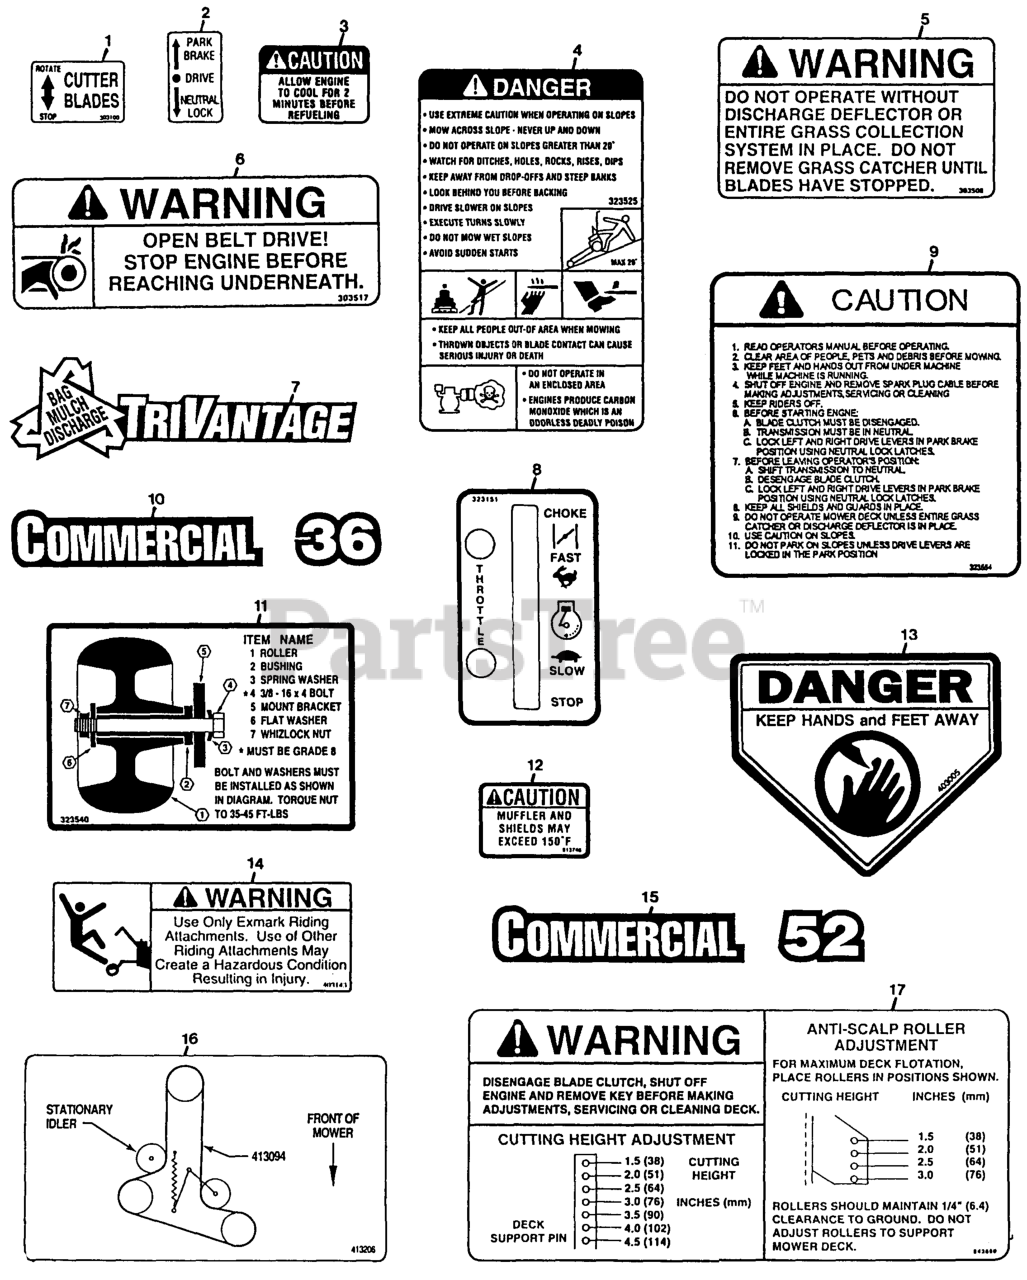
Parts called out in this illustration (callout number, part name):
1	DECAL,CUTTER BLADE
2	DECAL,NEUTRAL/BRAKE
5	DECAL-WARNING, DISCHARGE
6	DECAL,BELT DRIVE
10	DECAL,COMMERCIAL 36
11	DECAL,ROLLER MOUNTING
13	DECAL-DANGER
14	DECAL,SULKY WARNING
15	DECAL,COMMERCIAL 52
16	DECAL,BELT ROUTING
